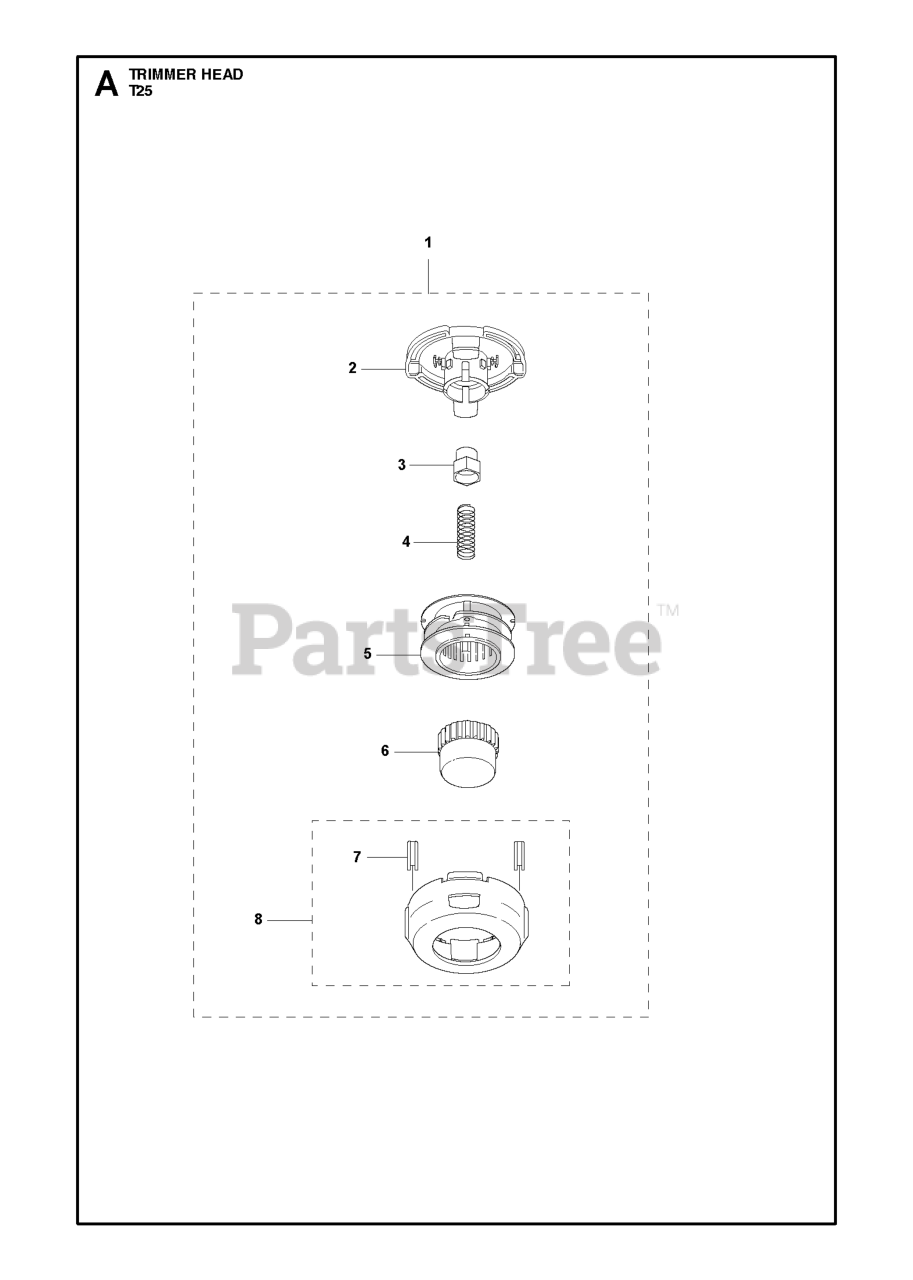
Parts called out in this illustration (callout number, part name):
1	T25 3/8" RH TRIMMER HEAD
1	T25 TRIM HEAD 10MM LH
3	ADAPTER
8	LID SPARE PART ASSY T25
